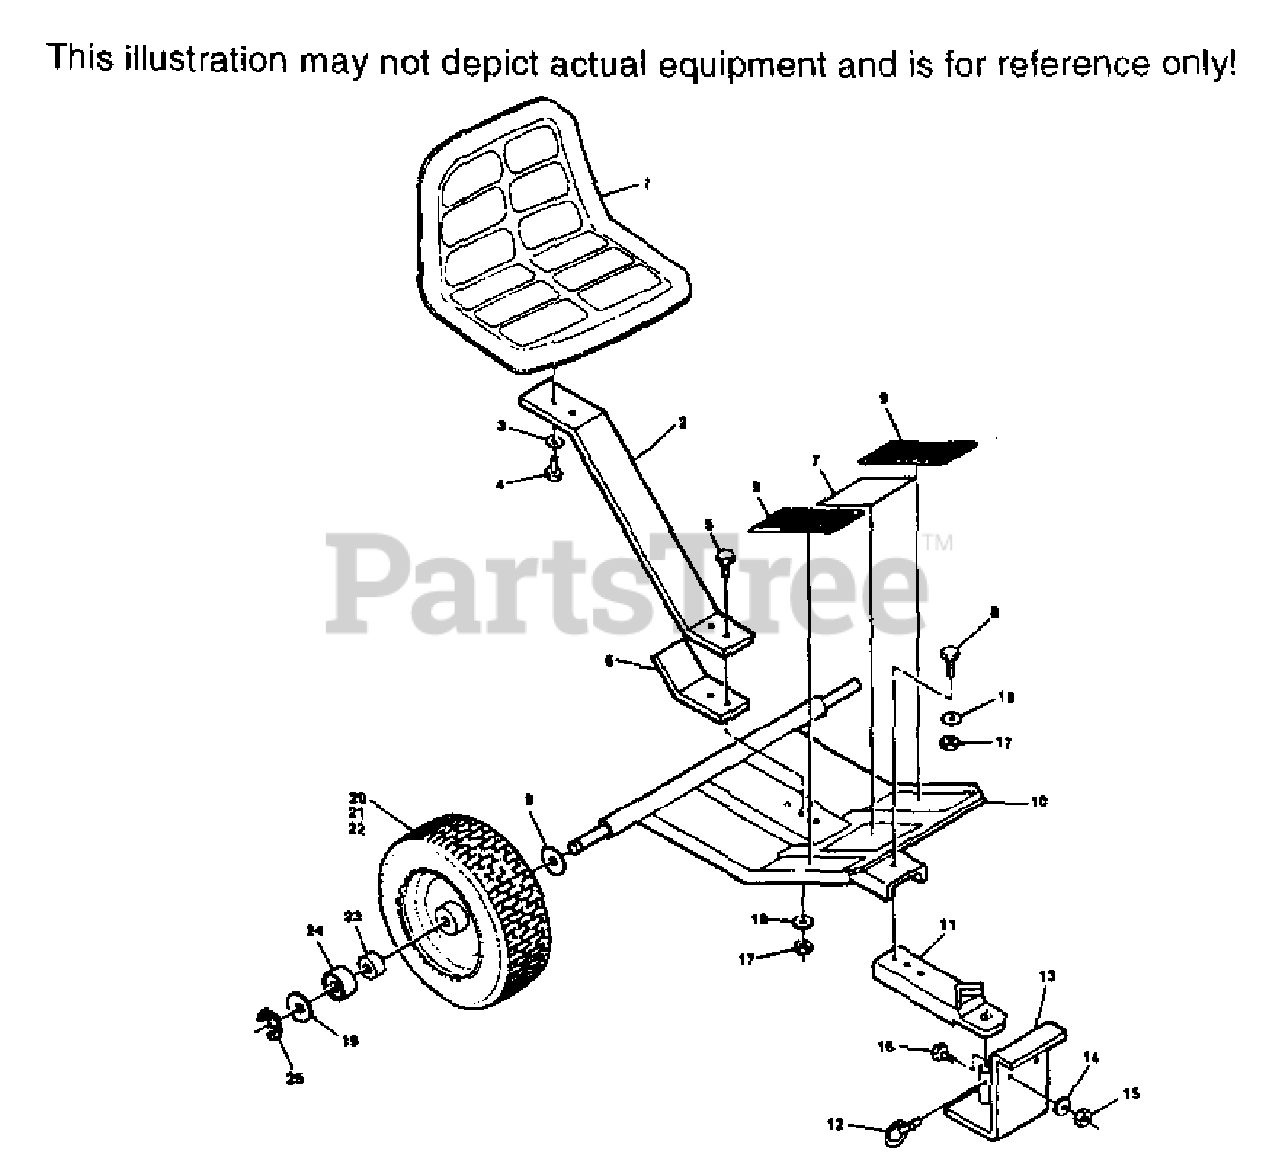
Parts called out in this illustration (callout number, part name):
1A	SEAT ASSEMBLY(2 HOLE)
1B	SEAT ASSEMBLY(1 HOLE)
2	SEAT SPRING
3	LOCKWASHER 1/2 SPRING
6	SPRING SUPPORT
7	DECAL
9	PAD, NON-SKID
10	FRAME WELDMENT
11	HITCH EXTENSION WELDMENT
12	QUICK PIN
13	MOUNTING BRACKET WELDMENT
14	LOCKWASHER 3/8 SPRING
18	LOCKWASHER 7/16 SPRING
19	WASHER 1-1/6 X 1-3/4 X .100
20	WHEEL ASSEMBLY(INCL. 21-24)
21	TIRE ONLY 16.3 X 4.80-8
22	RIM ONLY
23	BEARING ONLY
24	RETAINING CAP ONLY
25	RETAINING RING 1.00 EXT. "E"
